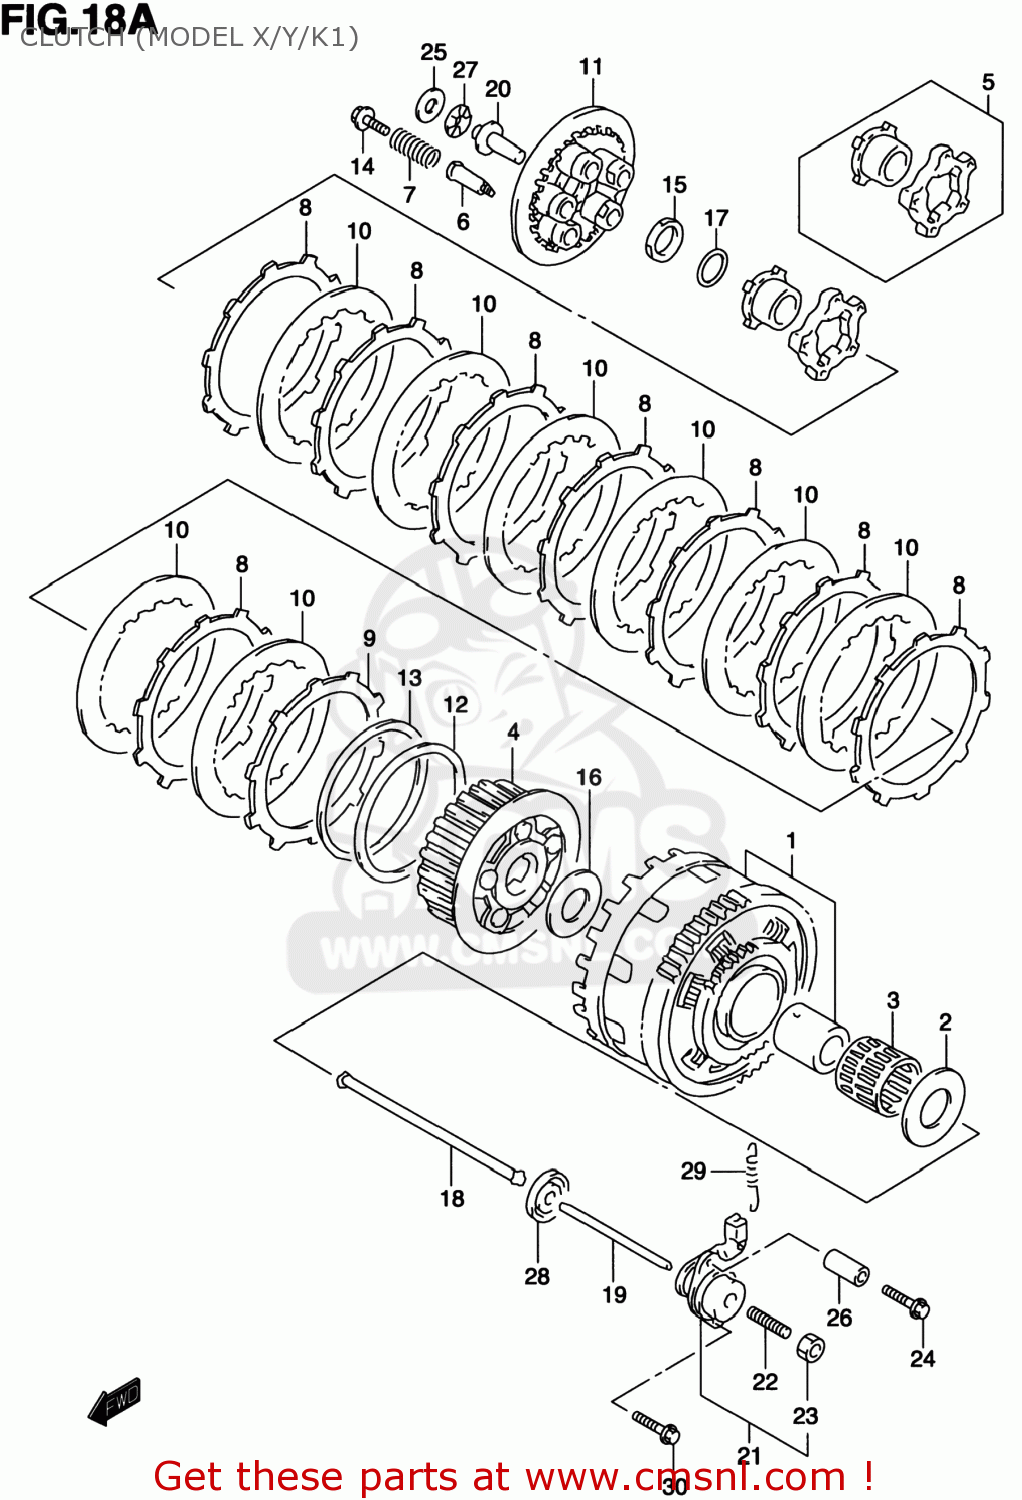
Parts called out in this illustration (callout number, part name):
1	GEAR ASSY,PRI DRIVEN
2	WASHER(25X54X2.5)
3	BEARING(35X40X35.8)
4	HUB,CLUTCH SLEEVE
5	CAM SET,CLUTCH
6	BOLT,SPRING SUPPORT
7	SPRING,CLUTCH
8	PLATE,CLUTCH DRIVE (NAS)
9	PLATE,CLUTCH DRIVE NO (NAS)
10	PLATE,CLUTCH DRIVEN (NAS)
11	DISC,CLUTCH PRESSURE
12	SEAT,WAVE WASHER
13	WASHER,CLUTCH PLATE WAVE
14	BOLT,CLUTCH SPRING
15	NUT
16	WASHER(25X50X2.5)
17	WASHER
18	ROD,CLUTCH PUSH,R
19	ROD,CLUTCH PUSH
20	PIECE,CLUTCH PUSH
21	SCREW ASSY,CLUTCH RELEASE
22	SCREW(6X25)
23	NUT
24	BOLT
25	WASHER(15.5X28X1)
26	SPACER(6.2X12X50)
27	BEARING(15X28X2)
28	SEAL,OIL(6X34X5.5)
29	SPRING
30	BOLT
